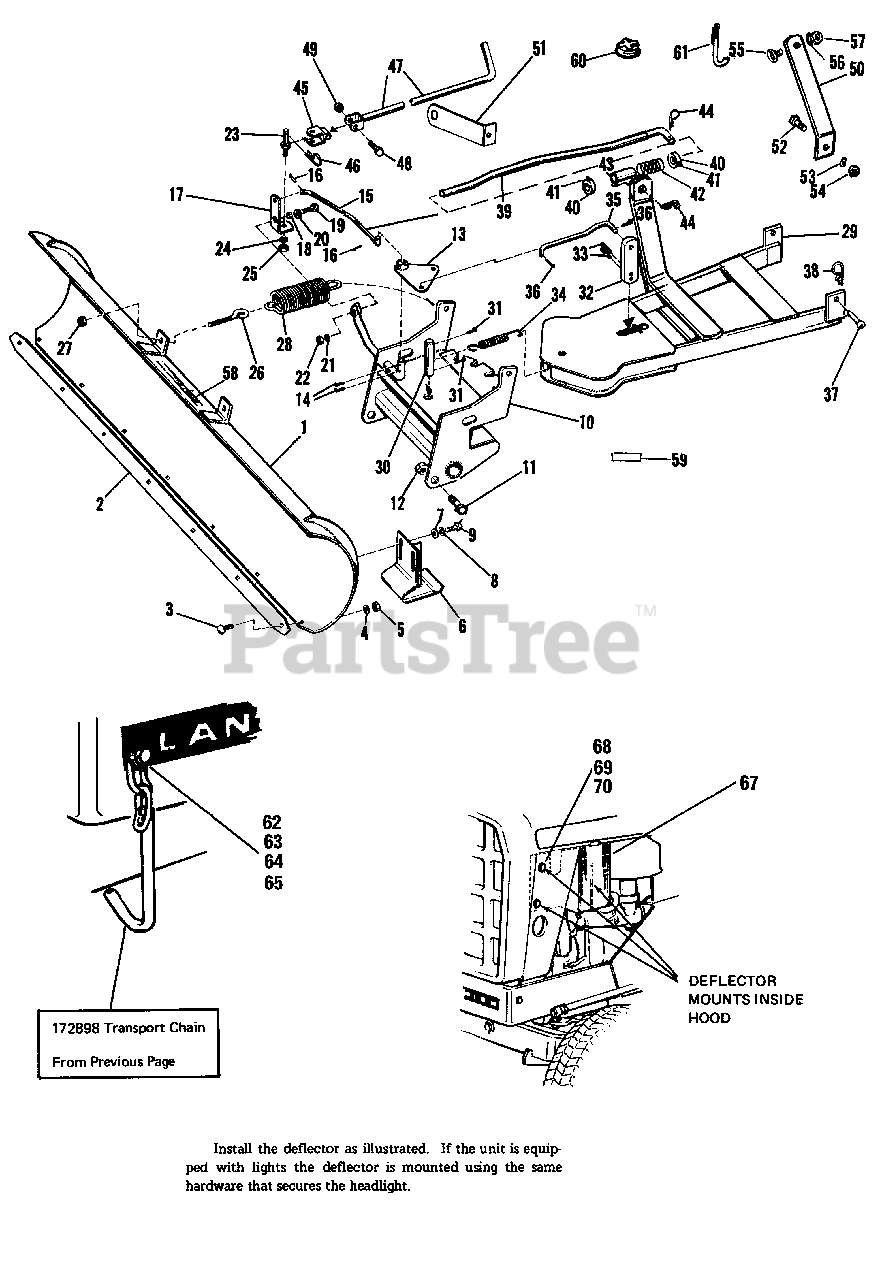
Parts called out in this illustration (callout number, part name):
1	Blade Assy.
3	Carriage Bolt, 3/8"-16 x 1"
4	Lock Washer, 3/8"
5	Hex Nut, Full 3/8"-16
6	Shoe Assy.
7	Flat Washer, 3/8"
8	Lock Washer, 3/8"
9	Hex. Cap Screw, 3/8"-16 x 3/4"
10	Pivot Frame Assy.
11	Hex Capscrew, 1/2"-13 x 1-1/2"
12	Hex Nut, 1/2"-13
13	Pivot Plate Assy.
14	Cotter Pin 1/8" x 1"
16	Cotter Pin, 3/32" x 5/8"
17	Pivot Arm
19	Hex Capscrew, 5/16"-18 x 1"
20	Plain Washer, 5/16"
21	Lock Washer, 5/16"
22	Hex Nut, Full, 5/16"-18
24	Lock Washer, 5/16"
25	Hex Nut, Full, 5/16"-18
27	Hex Nut, Full, 5/16-18
29	Push Bar Assy.
31	Cotter Pin, 3/16" x 1-1/4"
33	Roll Pin, 7/32" x 1"
34	Latch Spring
36	Cotter Pin, 3/32" x 5/8"
37	(Hitch) Pin
38	Hairpin Clip
39	Front Lift Rod
40	Collar
41	Set Screw 5/16"-18 x 1/2"
44	Hairpin Clip
46	Hairpin Clip
47	Handle Assy.
48	Hex Capscrew, 5/16"-18 x 1-1/2"
49	Full Lock Hex Nut 5/16"-18
50	Bracket (For 1971 Tractors Only)
52	Hex Capscrew, 3/8"-16 x 3/4"
53	Lock Washer, 3/8"
54	Hex Nut, Full 3/8"-16
56	Lock Washer, 1/4"
57	Hex Nut, Full, 1/4-20
58	Film, Simplicity
59	Model No. Plate
60	Fuel Tank Cap (Winterized)
61	Transport Chain Assy.
62	Hex Capscrew, 3/8"-16 x 1-1/2"
64	Plain Washer, 3/8"
65	Lock Washer, 3/8"
66	Hex Nut, Fun, 3/8"-16
67	Deflector
68	Hex Capscrew, 1/4"-20 x 1/2"
69	Lock Washer, 1/4"
70	Hex Nut. 1/4"-20
